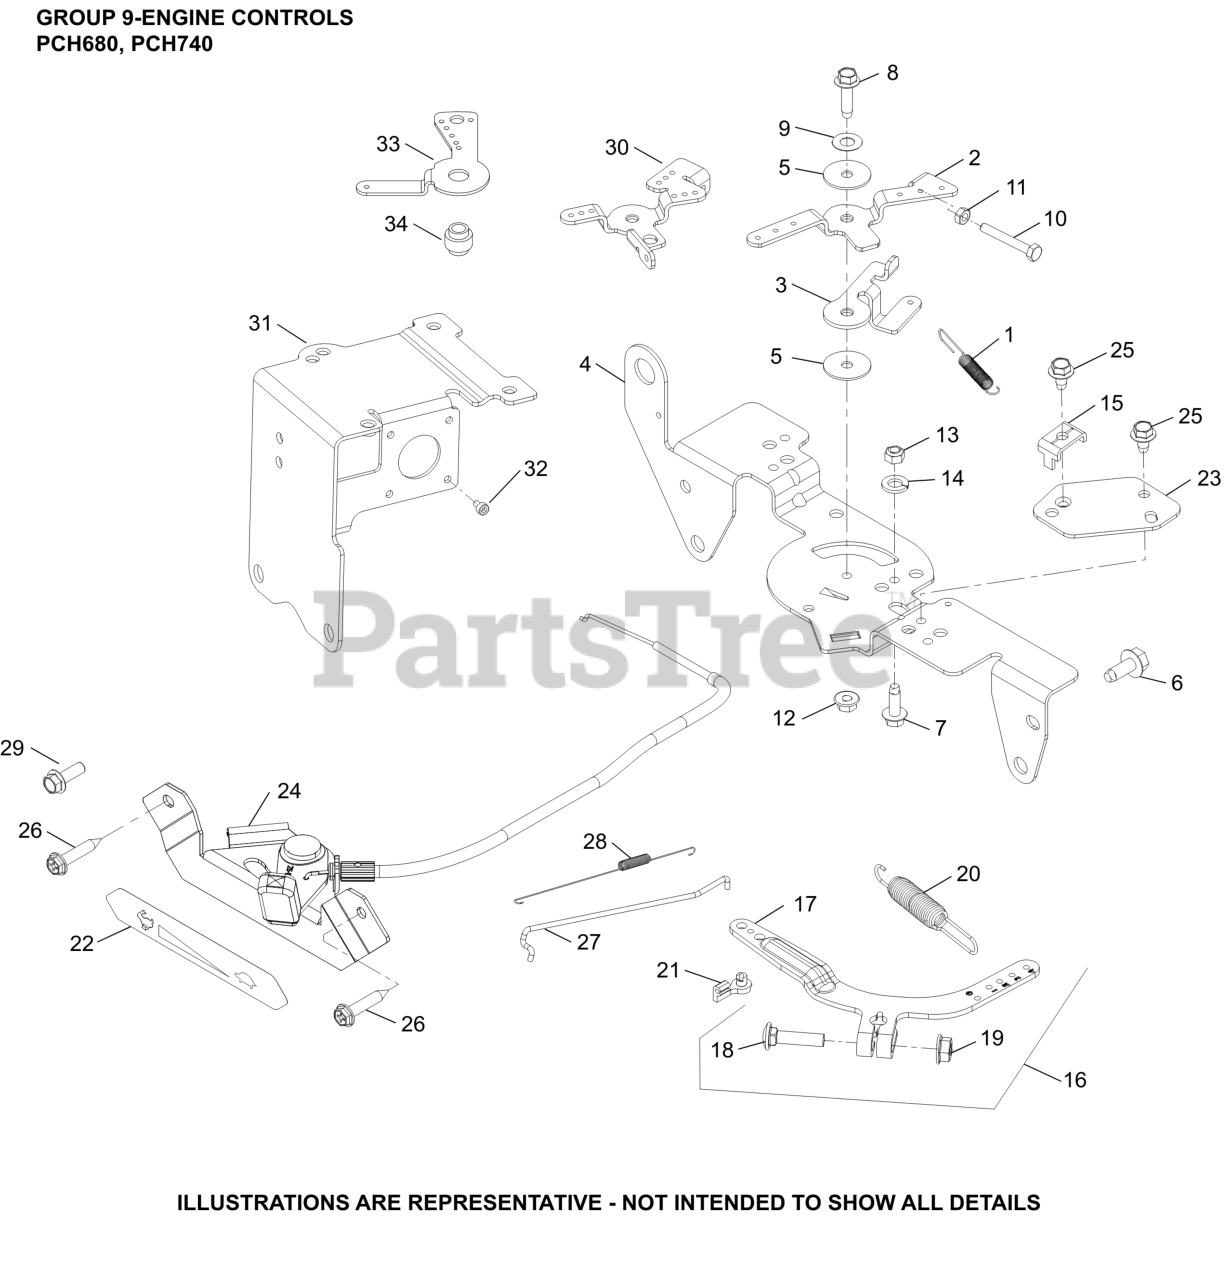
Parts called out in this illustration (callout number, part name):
16	LEVER, GOVERNOR ASSEMBLY
17	LEVER, GOVERNOR - (#2409069S)
18	BOLT, RD HD SQ NECK M6X1.0X25
19	NUT, FLG M6X1.0
20	SPRING, GOVERNOR (BLACK)
21	BUSHING, THROTTLE LINKAGE
27	LINKAGE, THROTTLE
28	SPRING, LINKAGE
NI	ROD, SPEED CONTROL
NI	NUT, ADJUSTING
NI	NUT, MACH SCREW #10-32 GRD 2
